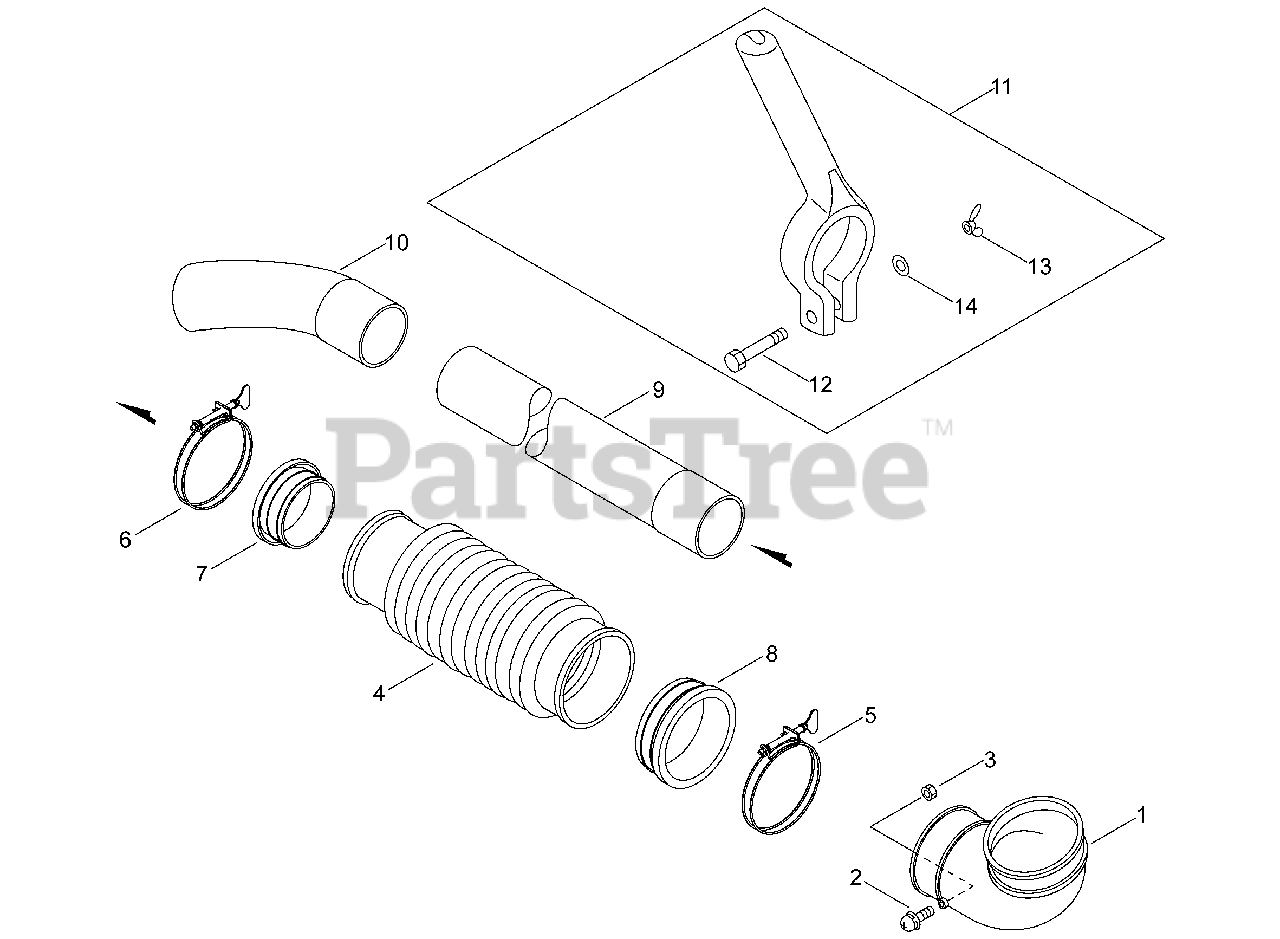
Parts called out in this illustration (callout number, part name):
1	TUBE, BLOWER - ELBOW
2	SCREW 5×14
4	TUBE, FLEXIBLE
5	CLAMP Ø95-Ø105
6	CLAMP Ø75-Ø85
9	TUBE, BLOWER - STRAIGHT
10	TUBE, BLOWER - CURVED
11	HANDLE, FRONT
12	+BOLT 6×45
13	+NUT, WING 6
14	+WASHER 6.5×11.5×0.8
